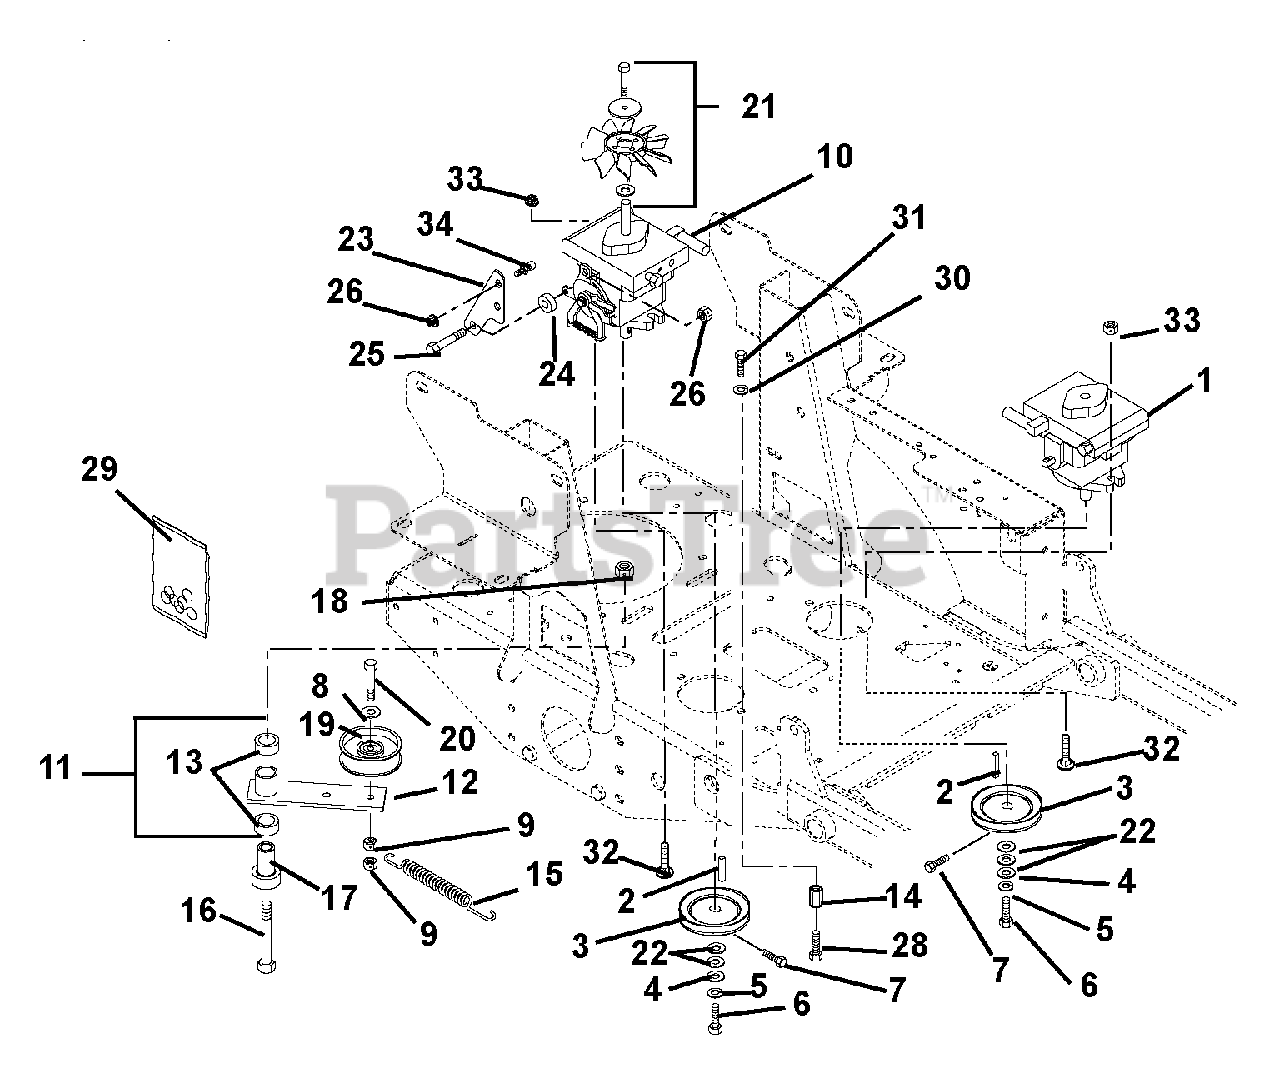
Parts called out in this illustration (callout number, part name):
1	Pump, Hydraulic BDP-10A Left Hand
2	Key, Straight 5mm x 25mm x 5mm
3	Sheave 4.0 x .199
4	Washer, Flat Steel .281 x 1.00 x .063
5	Washer, Locking .25 x .062
6	Bolt, Hex M6 x 1.00 x 12
7	Bolt, Hex .25-20 x .50 Grade 5
8	Washer, Flat Steel .39 x .75 x .125
9	Nut, Nyloc Flange 3/8-16
10	Pump, Hydraulic BDP-10A Right Hand
11	Assembly, Idler Arm Guard Drive
12	Weldment, Idler Arm Ground Drive
13	Bearing, 1.00 x 1.12 x .75
14	Nut, Coupling .375-16 x 1.75
15	Spring, Tension .120 x .845 x 6.50
16	Bolt, Hex .50-13 x 3.50 Grade 5
17	Bearing, Pedestal Powdered Metal
18	Nut, Nyloc Flange .50-13
19	Idler, Flat 4.00 x 1.06
20	Bolt, Hex .38-16 x 2.25 Grade 5
21	Fan, Cooling
22	Washer, Flat Steel .656 x 1.31 x .095
23	Bracket, Return to Neutral/Damper
24	Spacer .344 x 1.00 x .375
25	Bolt, Hex .31-18 x 1.25 Grade 5
26	Nut, Nyloc Flange 5/16-18
27	Washer, Flat Steel .344 x .688 x .065
28	Bolt, Hex .38-16 x 1.50 Grade 5
29	Kit, Pump Seal (BDP-10A)(One kit required for each pump)
30	Washer, Locking .38 x .094
31	Bolt, Hex .38-16 x .75 Grade 5
32	Bolt-Round Head Square Neck .44-14 x 1.50 Grade 5
33	Nut, Nyloc Flange .44-14
34	Stud, Ball
